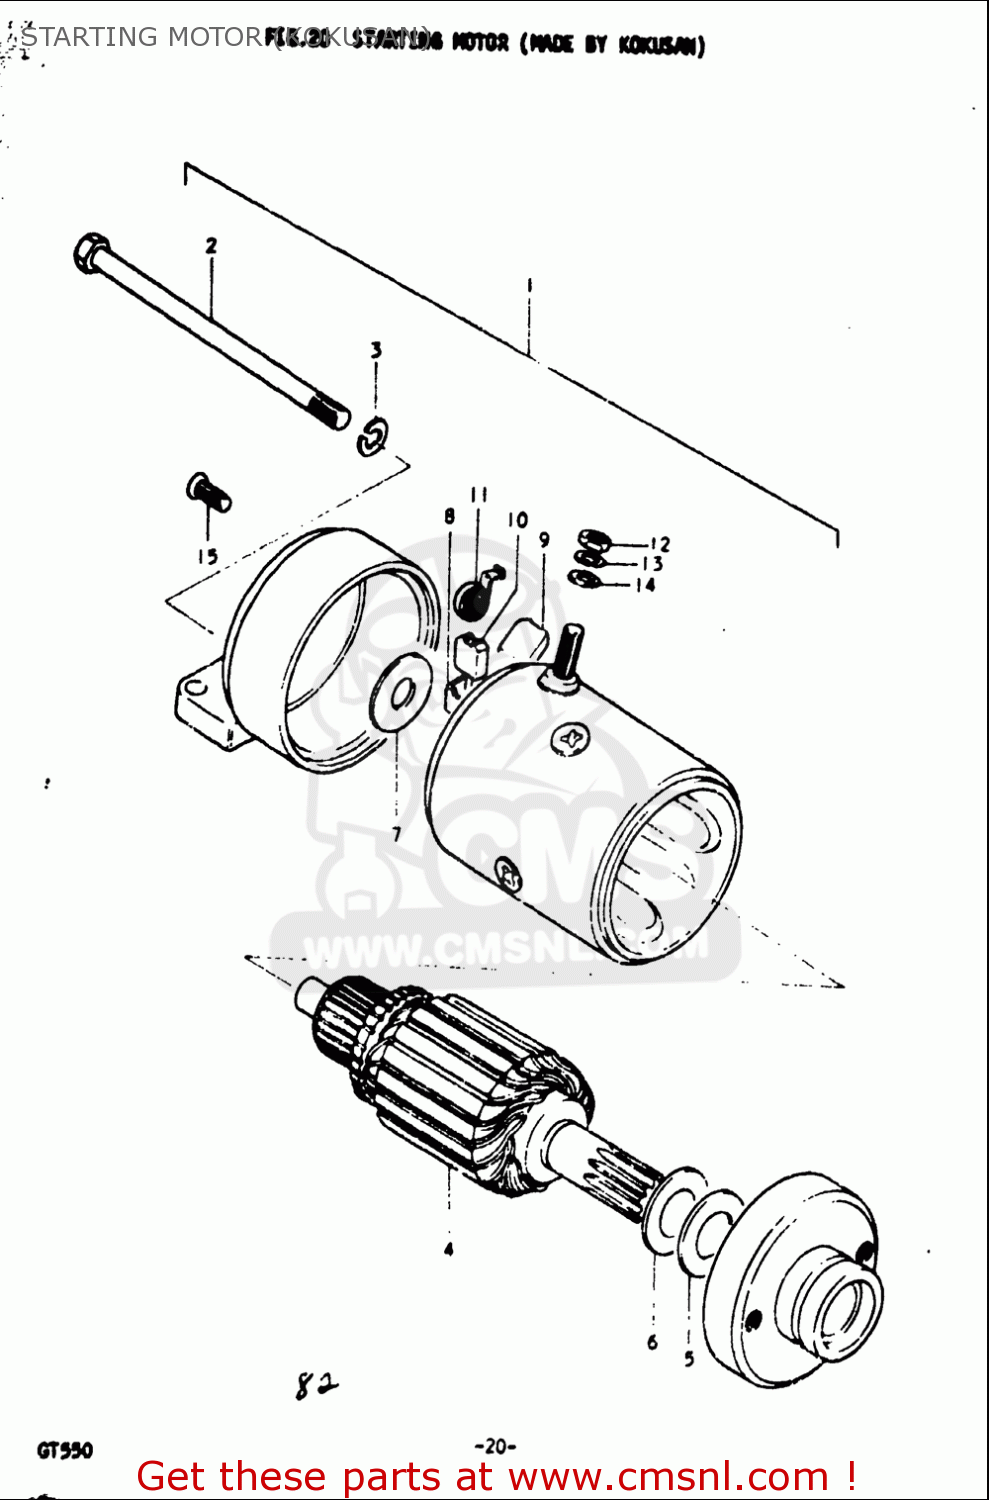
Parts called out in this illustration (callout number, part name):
3	WASHER,LOCK
9	BRUSH (+)
12	NUT
13	WASHER,LOCK
14	WASHER
15	SCREW
